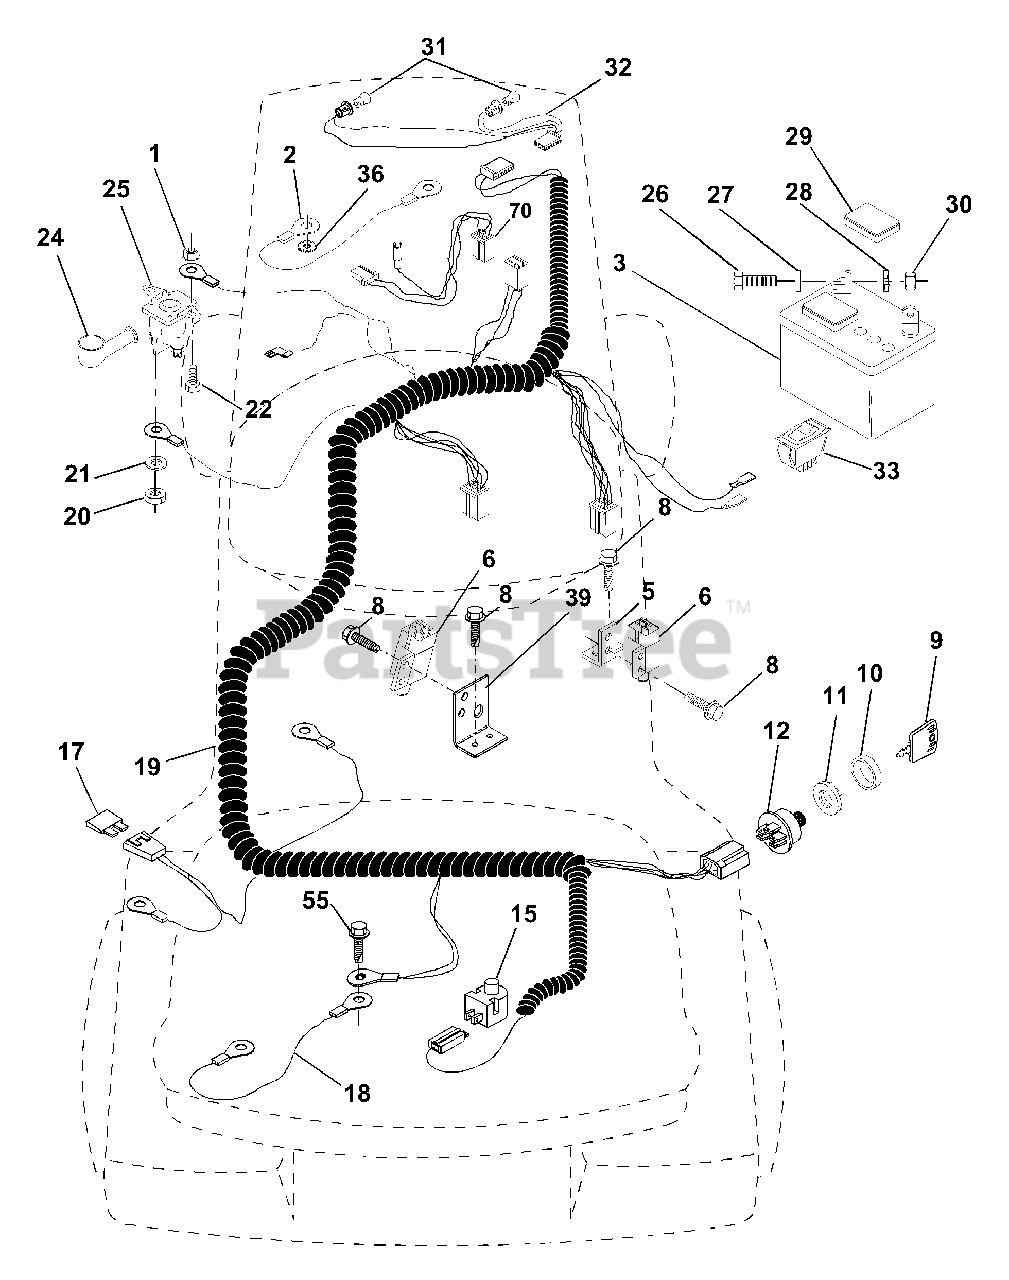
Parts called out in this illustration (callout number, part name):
1	Nut, Hex Keps 1/4-20
2	Assembly, Cable
3	Battery
5	Bracket, Switch
6	Switch, Interlock (4-terminal)
8	Screw, Hex Hd. Tap #10-24 x 1/2
9	Key, Steel Delta
10	Cover, Key Ignition
11	Nut, Ignition
12	Switch, Ignition
15	Switch, Plunger
18	Assembly, Cable
19	Harness, Ignition
20	Nut, Hex Jam 1/4-20
21	Washer, Lock 1/4
22	Bolt, Fin. Hex 1/4-20 UNC x 1/2
24	Cover, Terminal
25	Solenoid
26	Bolt, Hex Hd. 1/4-20 UNC x 3/4
27	Washer 9/32 x 5/8 x 16
28	Washer, Lock 1/4
29	Cap, Battery
30	Nut, Fin. Hex 1/4-20 UNC
31	Bulb, Light
32	Harness, Headlight
33	Switch, Light
36	Washer Lock Inter. Tooth 1/4
39	Bracket, Switch Clutch
55	Screw Thdrol 5/16-18 x 1/2
70	Harness Engine
